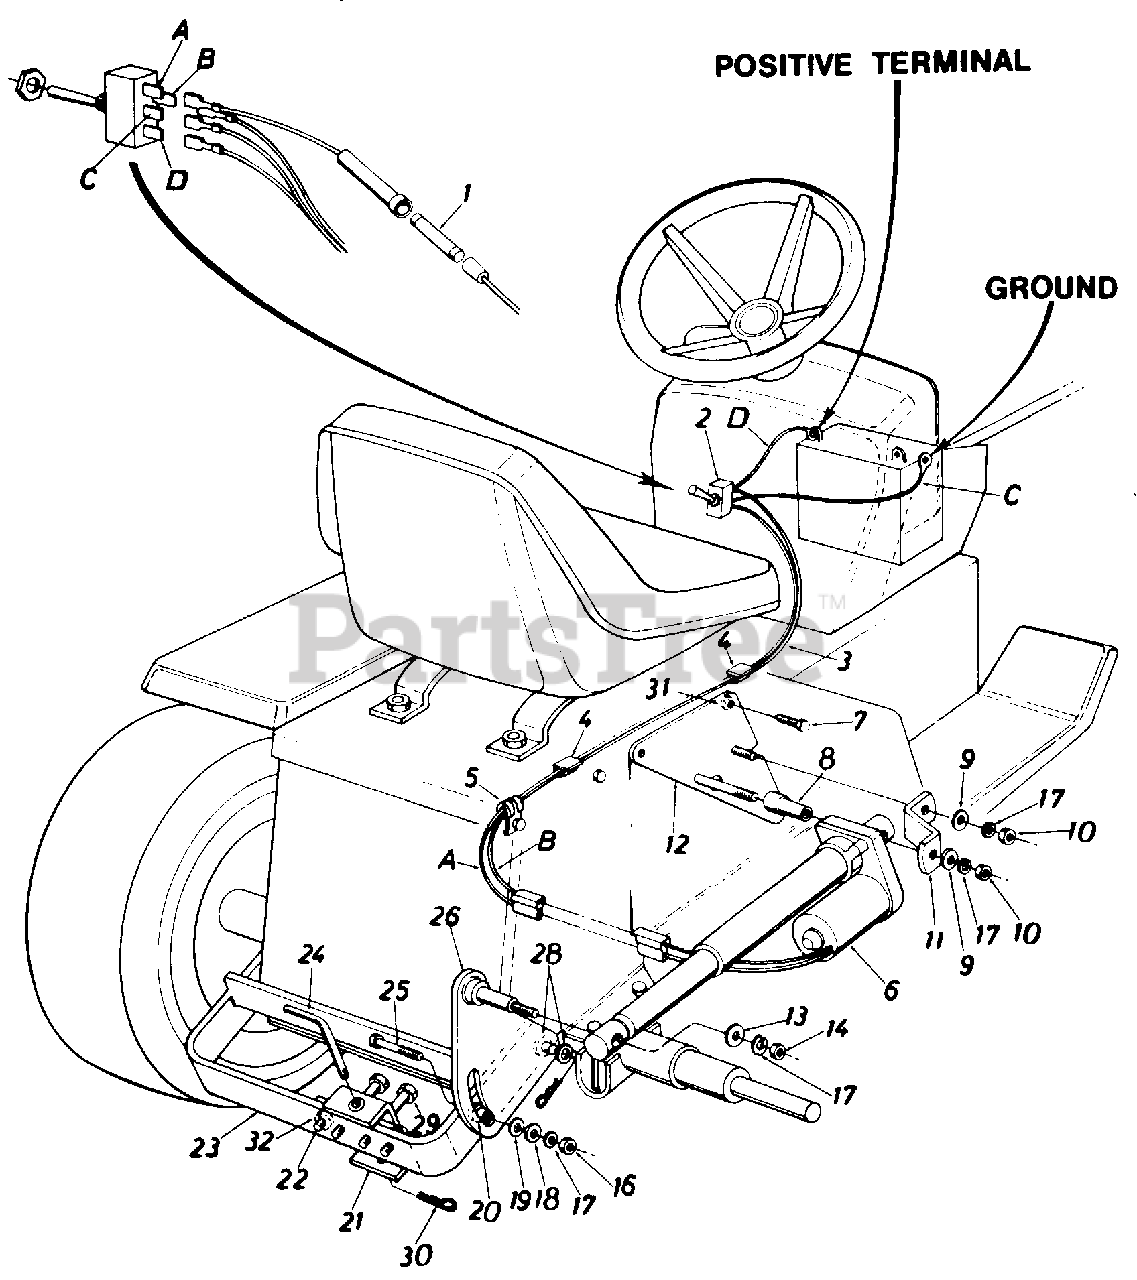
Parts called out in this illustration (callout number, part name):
1	Fuse 30 AMP
2	Toggle Switch
3	Wire Harness
4	Adjustment Clamp
5	Clamp
6	Electric Actuator
7	Hex Wash. TT. Tap Scr. 5/16 x .62" Lg.
8	Spacer Special for Actuator
9	Fl.-Wash. .378" I.D. x 1.00" O.D. x .125 Thk.
10	Hex Nut 3/8-16 Thd.*
11	Bracket Actuator Mounting
12	Mounting Plate Ass'y.
13	Fl.-Wash. .385" I.D. x .87" O.D. x .060 (H.T.)
14	Hex Nut 3/8-16 Thd.*
16	Hex Nut 3/8-16 Thd.*
17	L.-Wash. 3/8" I.D.*
18	Fl.-Wash. .378" I.D. x 1.00" 0.D. x .125" Thk.
19	Fl.-Wash. .635 I.D. x 1.00" O.D. x .030" Thk. (H.T.)
20	Shoulder Spacer
23	Hitch BarAss'y.
24	Hitch Pin
25	Hex Bolt 3/8-16 x 1.75" Lg.*
26	Lifting Plate Ass'y.
28	Fl.-Wash. .63" I.D. x 1.12" O.D. x .100 Thk.
29	Hex Bolt 1/2-13 x 3.00" Lg.*
30	Intern. Cotter Pin 5/8" Dia.
31	Fl.-Wash. .378" I.D. x 1.00" O.D. x .125
32	L-Wash. 1/2" I.D.*
